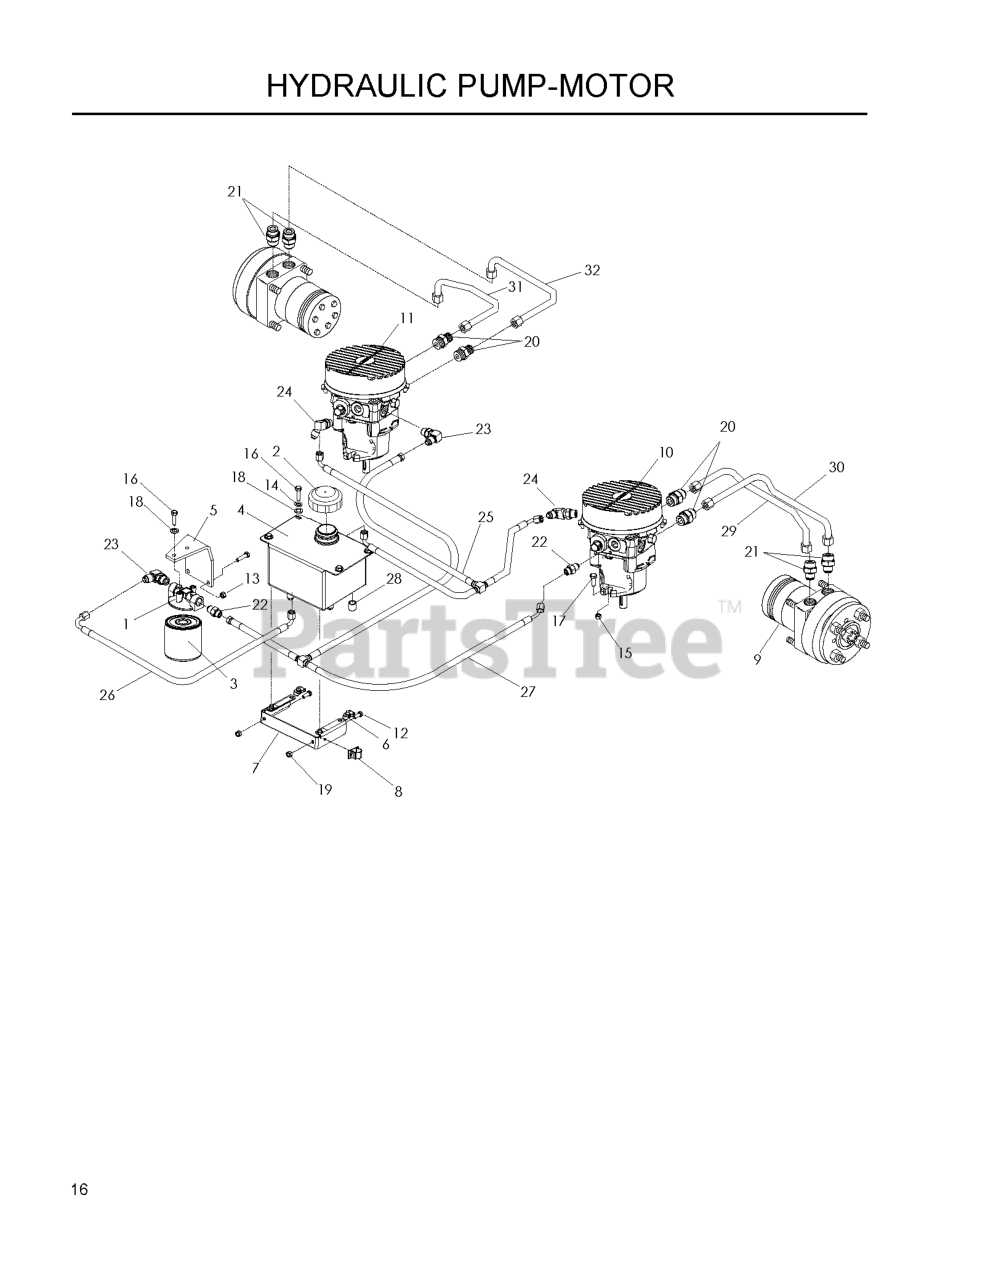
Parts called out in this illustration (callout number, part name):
1	FILTER HEAD
2	HYDRAULIC CAP
3	HYDRAULIC OIL FILTER
5	OIL FILTER BRKT
6	1/4C - U TYPE RETAINER
7	TANK MOUNT
8	PUSH-MOUNT WIRE CLIP
9	TL15 WHEEL MOTOR
10	HG_PUMP, 10CC W/FAN LEFT
11	HG_PUMP, 10CC W/FAN RIGHT
12	HCS 5/16C X 3/4
13	NUT.1/4-20.HEX.NYLOC.ZD
14	LOCKWASHER 1/4"
15	NUT 3/8C CENTERBLOCK
16	HCS 1/4C X 3/4 HCS
17	4CS 3/8C X 1 SERRATED HEAD
18	WASHER 1/4 FLAT
19	NUT 5/16 NYLOC
20	FITTING, STRAIGHT F6400-8-8-0
22	HYDRAULIC FITTING
23	ELBOW, F6801-6-6-0 90 DEGREE
24	45 DEG ADJ ELBOW
25	HOSE, T-ASM RETURN
26	HOSE, TANK - FILTER LINE
27	HOSE, T-ASM SUPPLY
28	NUT 9/16-18 JIC CAP
29	HOSE, RPA - MA LINE
30	HOSE, RPB - MB LINE
31	HOSE, LPA - MB LINE
32	HOSE, LPB - MA LINE
